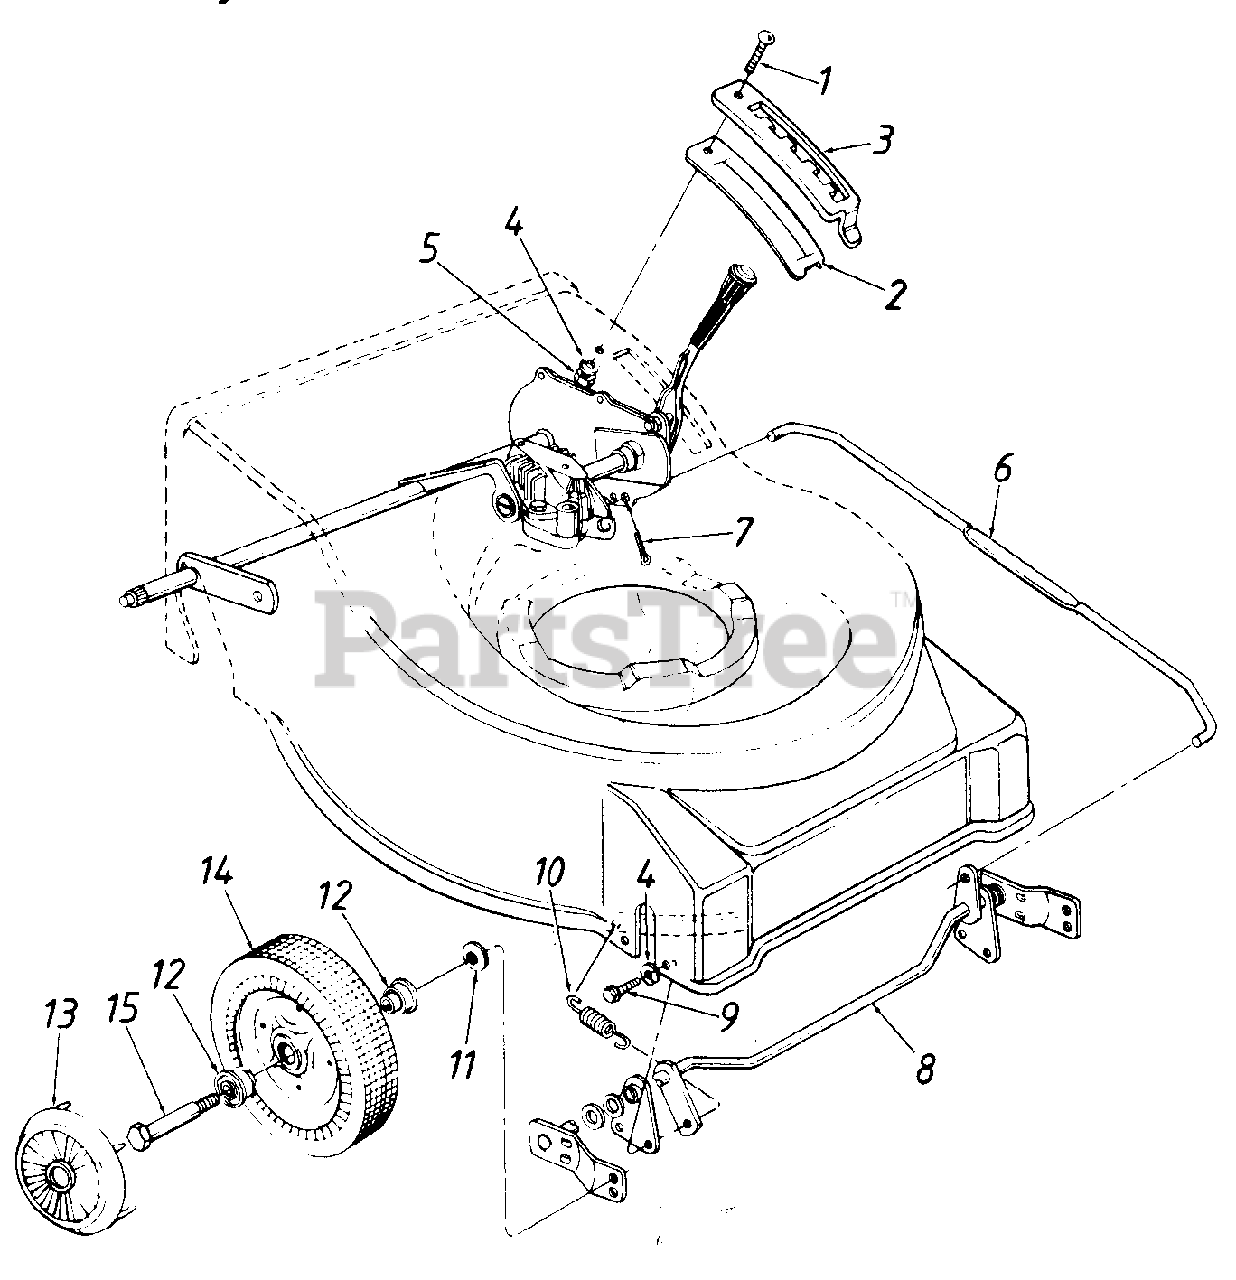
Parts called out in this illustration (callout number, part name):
1	Torx Mach. AB-Tap Scr. 1/4 x .62" Lg.
2	Height Adjustment Support
3	Height Adjustment Plate
4	L-Wash. 1/4" I.D.
5	Hex Nut 1/4-20 Thd.
6	Height Adj. Connecting Rod
7	Cotter Pin 3/32" Dia.
9	Hex L-Wash. Hd. AB-Tap Scr. 1/4 x .38" Lg.
10	Extension Spring 2.39" Lg.
11	Bell-Wash. .380" I.D. x .88" O.D.
12	Flange Ball Bearing 1/2" I.D.
13	Hub Cap
14	Wheel Ass'y. Comp.-Front
15	Shld. Bolt .498" Dia. x 1.45"
